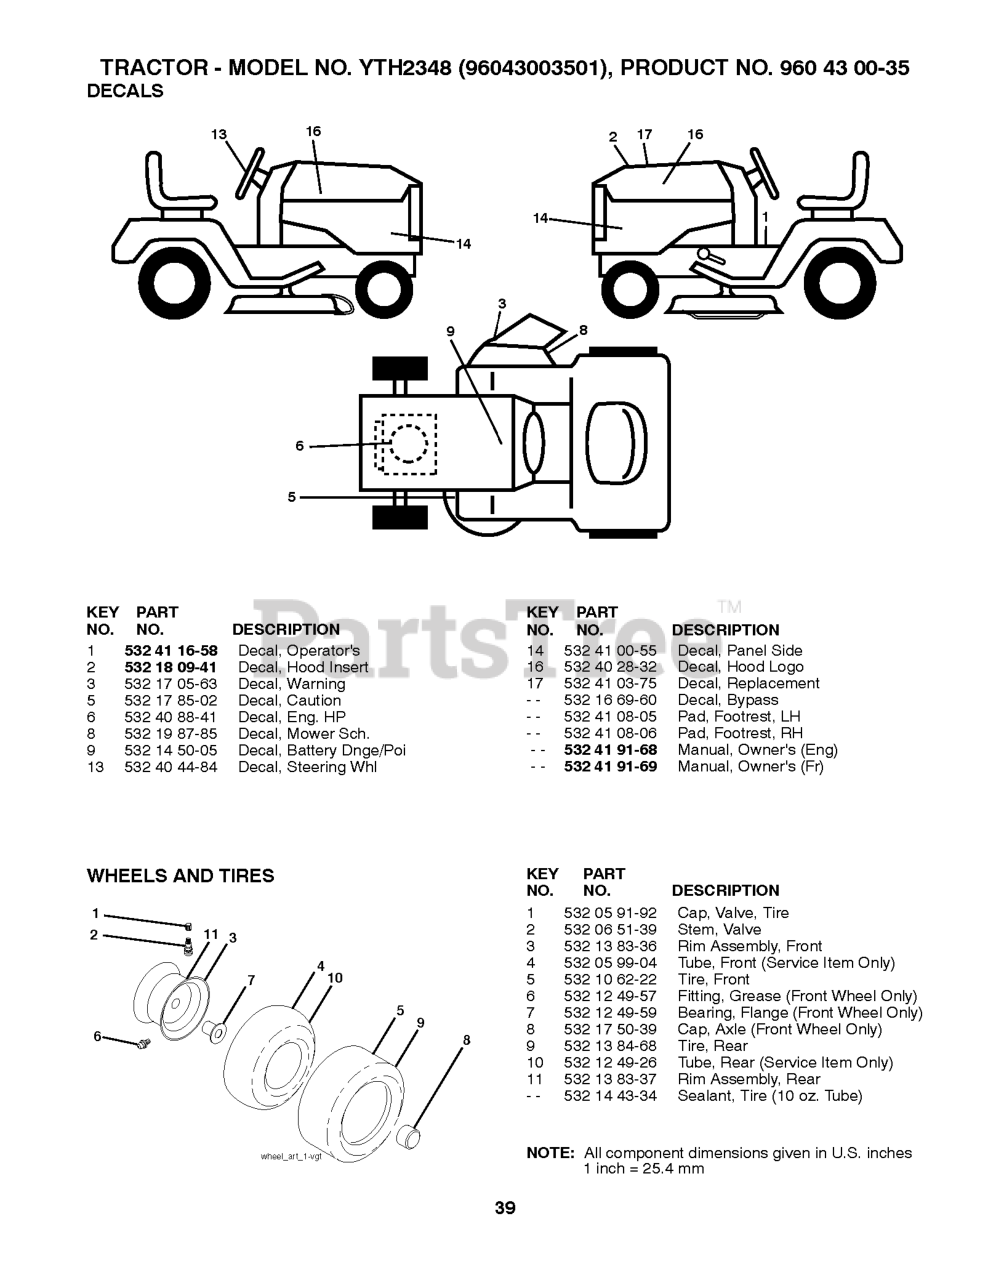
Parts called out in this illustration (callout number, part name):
1	DECAL.FENDER.WARNING.ENG
2	DECAL HOOD CUST. RESP.
3	DECAL.WARN.KEEP.HAND.AWAY
5	DECAL CLUTCH/BRAKE
6	DECAL, ENG. HP
8	DECAL.MOWER.SCH.48/54
9	DECAL BTRY SYMBOLS
13	DECAL.WHEEL.STRG.LGN.H
14	DECAL, PANEL SIDE
16	DECAL.HOOD.NAMELOGO.HUSQ
17	DECAL.REPLACEMENT.960430035
